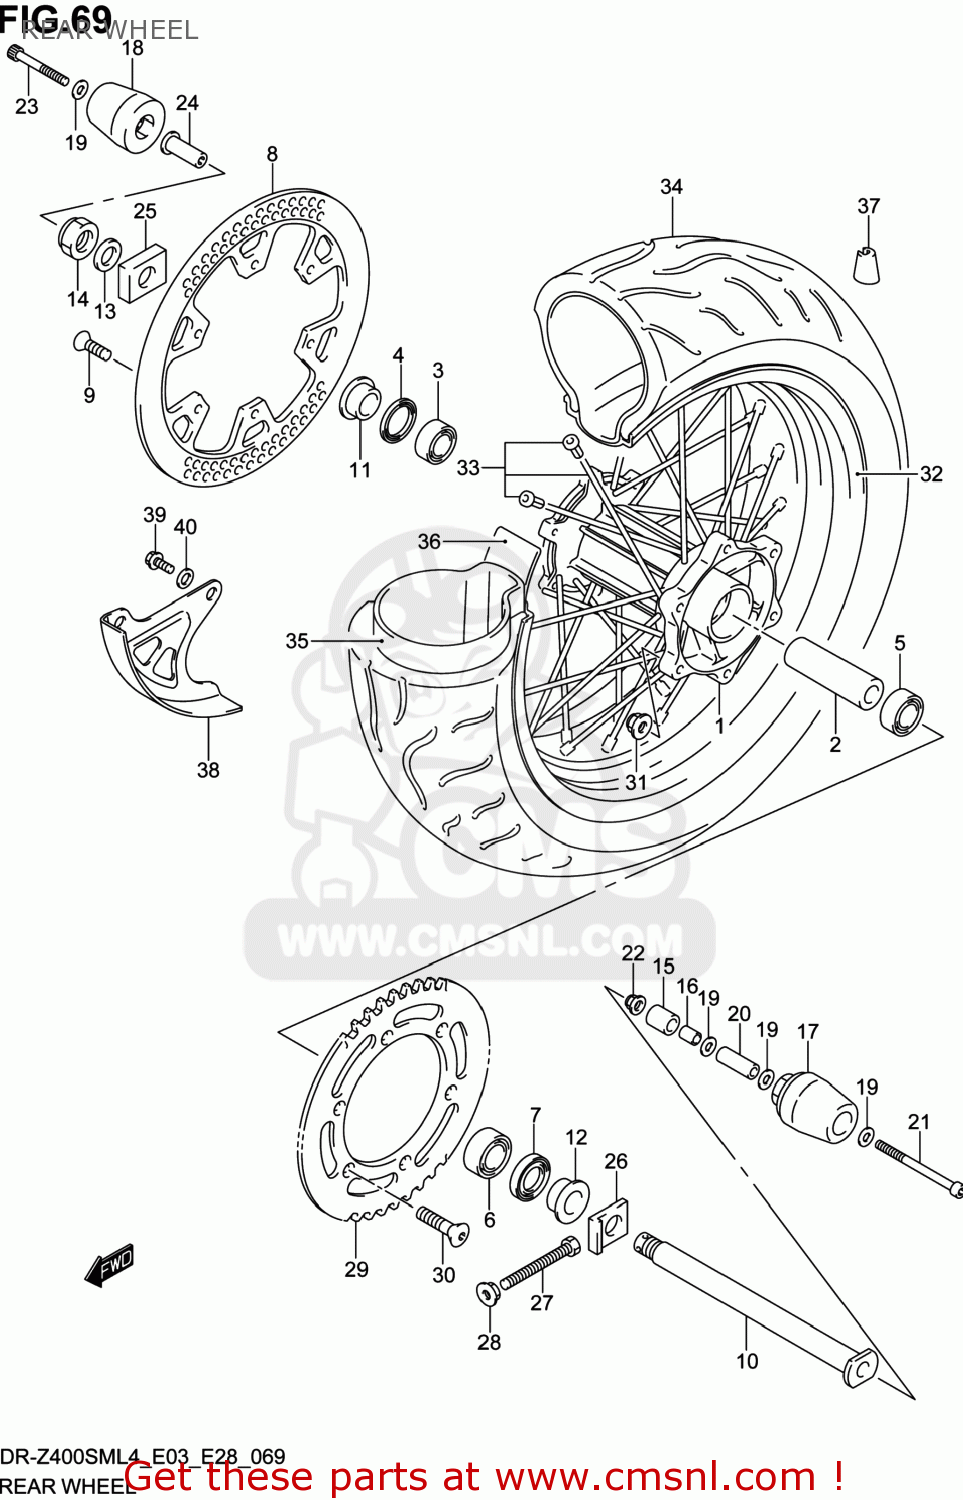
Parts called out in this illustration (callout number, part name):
1	HUB,RR WHEEL
2	SPACER,RR HUB BEARING
3	BEARING
4	SEAL(29X42X6)
5	BEARING
6	BEARING
7	SEAL,OIL(29X47X6)
8	DISC,RR BRAKE
9	SCREW(6X18)
10	AXLE,RR
11	SPACER,RR AXLE
12	SPACER,RR AXLE
13	WASHER(19X32X3.2)
14	NUT
15	EXPANDER,FR AXLE SLIDER,R
16	SPACER(5.5X8X10.5)
17	SLIDER,RR AXLE,L
18	SLIDER,FR AXLE,L
19	WASHER(5.5X12X0.8)
20	SPACER(5.5X9.5X26)
21	BOLT(5X65)
22	NUT
23	BOLT
24	NUT
25	ADJUSTER,CHAIN,R
26	ADJUSTER,CHAIN,L
27	BOLT(8X50)
28	NUT
29	SPROCKET,RR(NT:41)
30	BOLT(8X30.5)
31	NUT
32	RIM,RR WHEEL(17M/CXMT4.50 AL)
33	SPOKE SET,RR WHEEL
34	TIRE,RR(140/70R17M/C 66H)
35	TUBE ASSY,WHEEL INNER
36	PROTECTOR,WHL INR TUBE
37	BALANCER,WHEEL(20G)
38	COVER,RR DISC
39	BOLT(6X10)
40	WASHER
